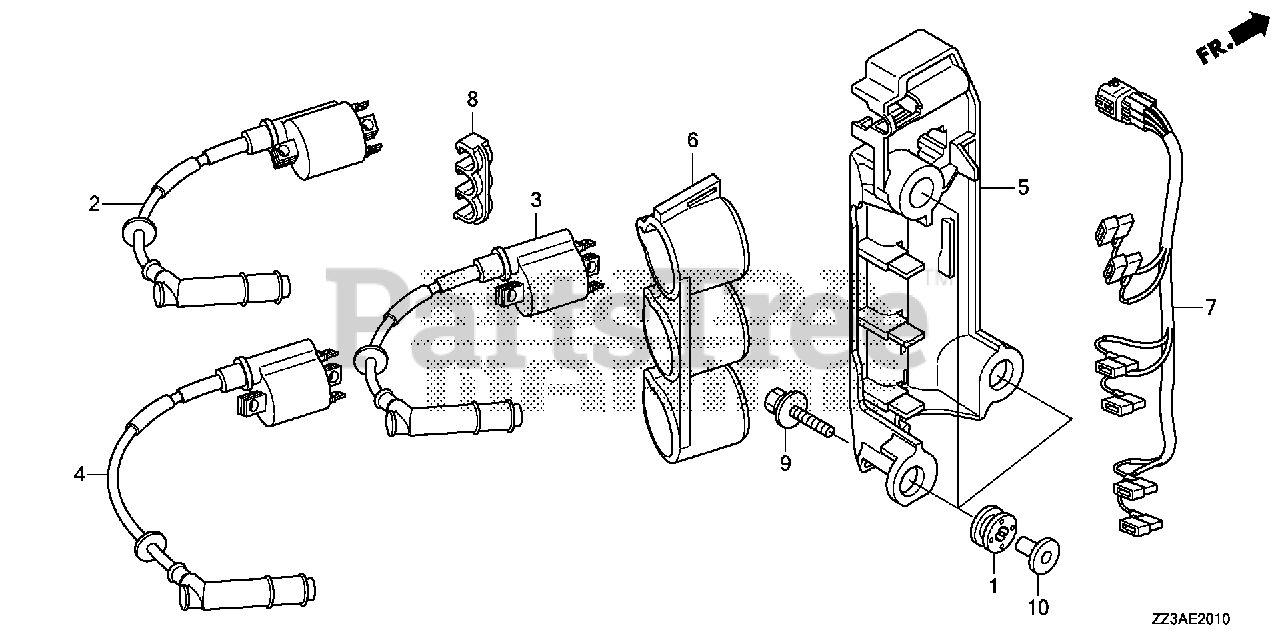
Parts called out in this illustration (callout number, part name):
1	GROMMET, ELECTRONIC PARTS CASE
2	COIL, IGNITION (1)
3	COIL, IGNITION (2)
4	COIL, IGNITION (3)
5	CASE, IGNITION COIL
6	SUSPENSION, IGNITION COIL
7	WIRE ASSY., IGNITION COIL
8	CLAMP, IGNITION WIRE
9	BOLT-WASHER (6X27) (CT200)
10	COLLAR, MODULE IGNITION CONTROL CASE (CDI)
